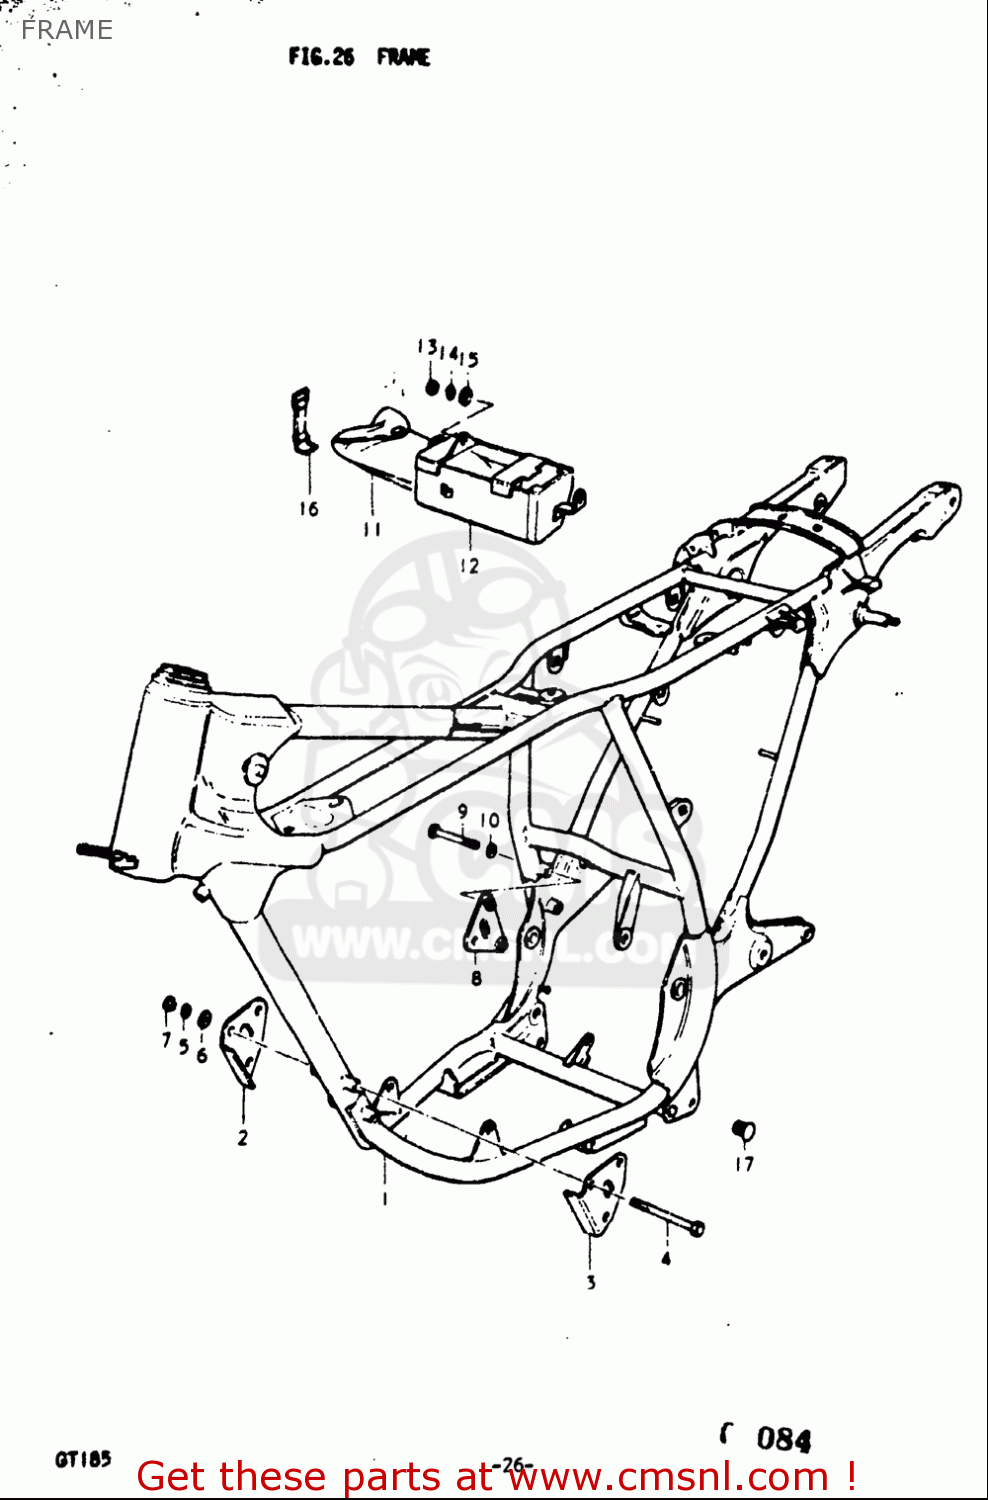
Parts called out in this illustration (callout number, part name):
4	BOLT
5	WASHER,LOCK
6	WASHER
7	NUT
9	BOLT
10	WASHER,LOCK
11	TOOL ASSY
13	NUT
14	WASHER,LOCK
15	WASHER
16	BAND
17	CAP(OD:14)
